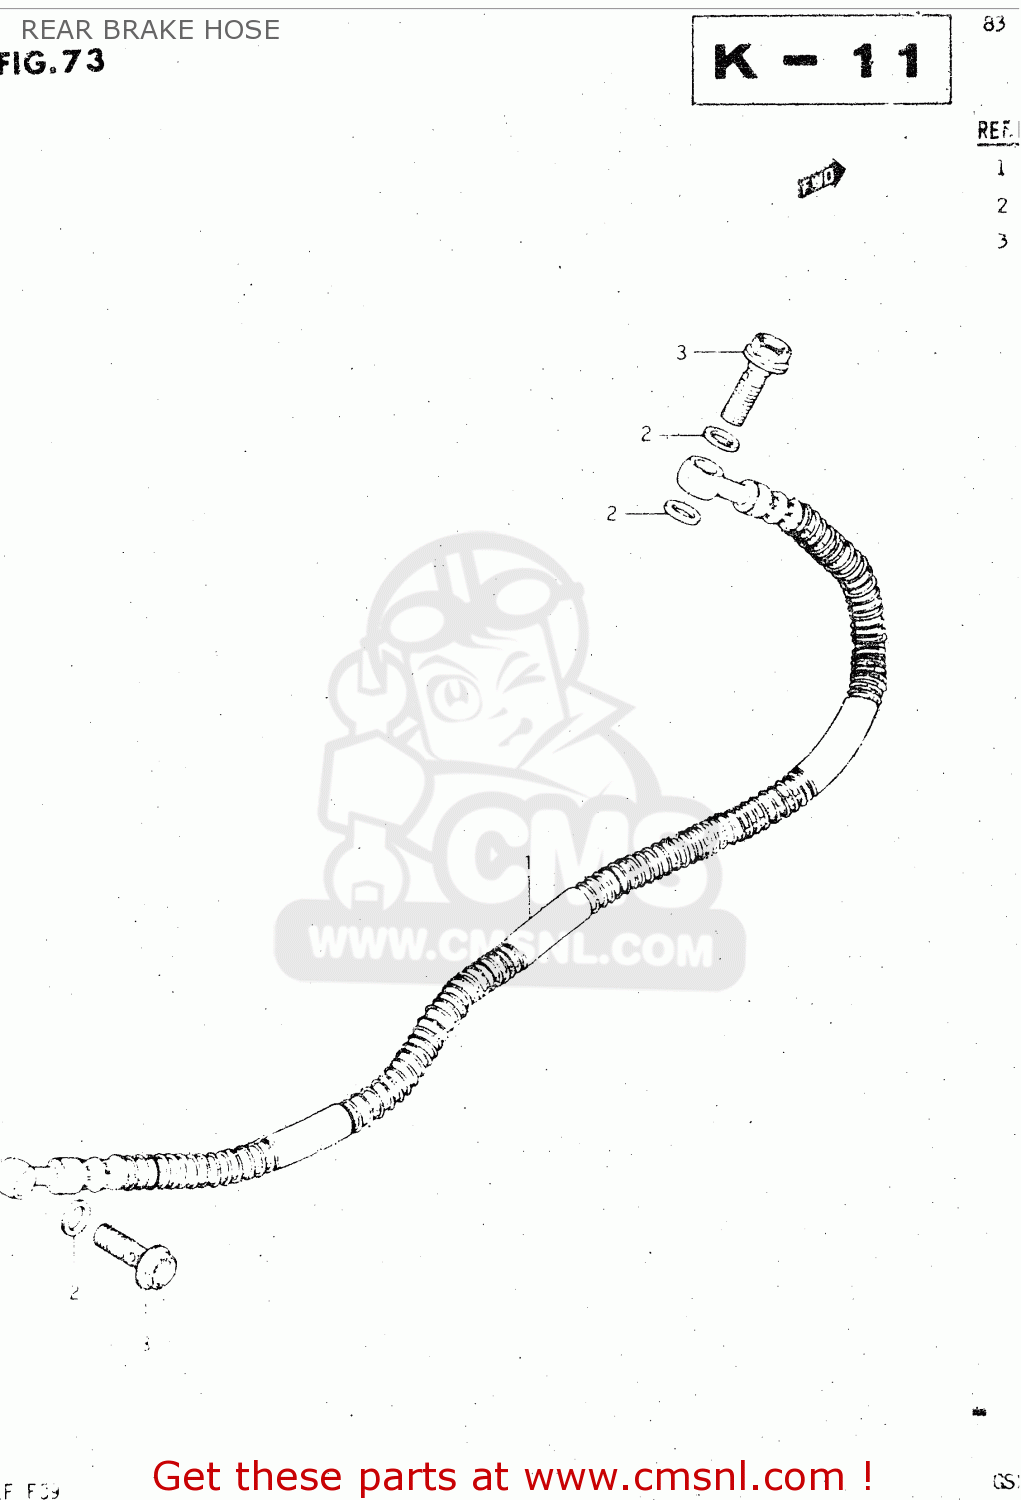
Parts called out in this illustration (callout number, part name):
1	HOSE,REAR BRAKE
2	WASHER(10X15X1.5)
3	BOLT UNION
